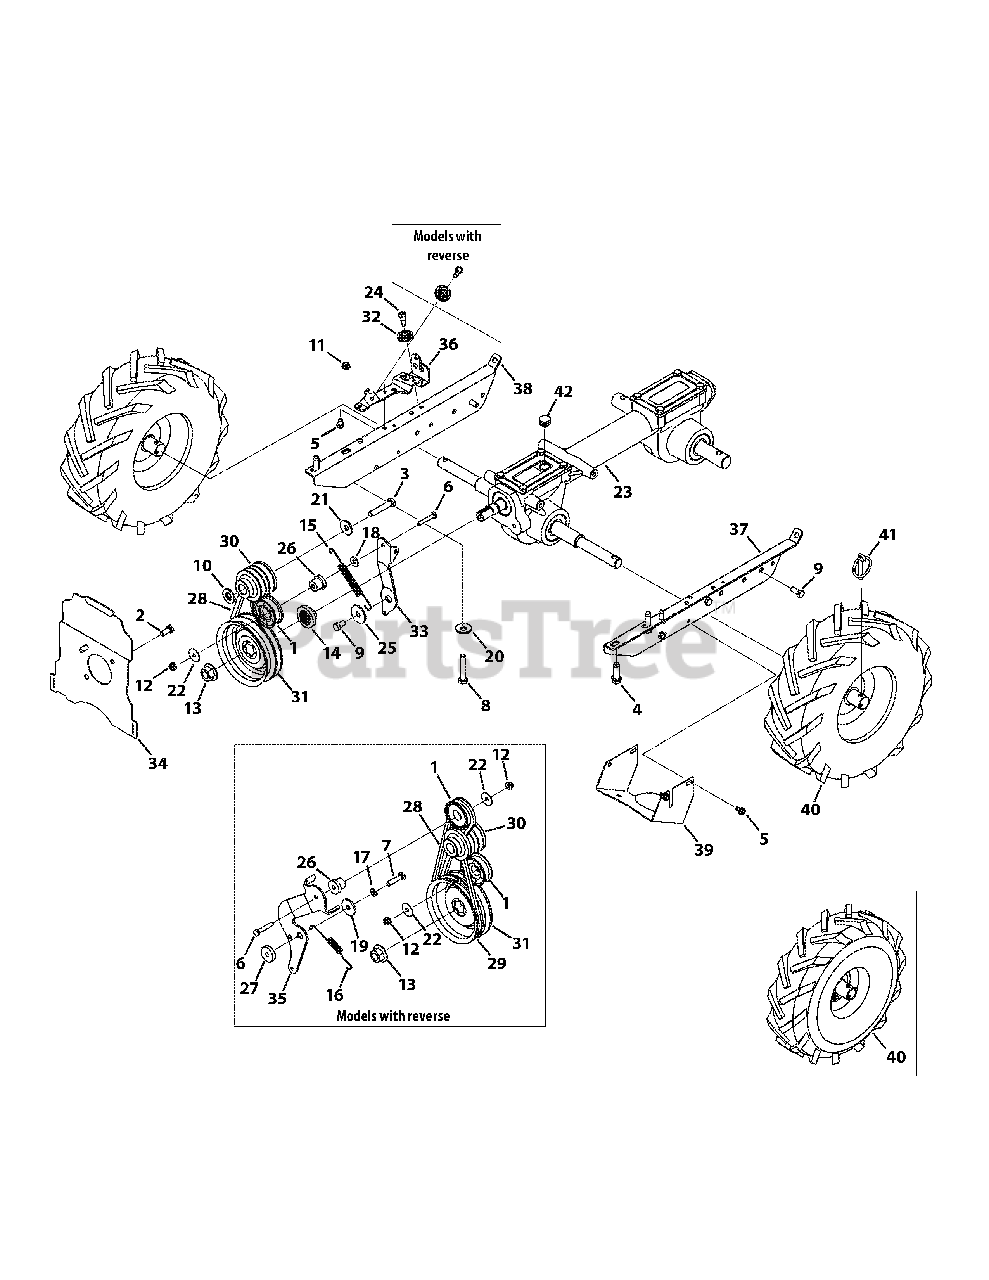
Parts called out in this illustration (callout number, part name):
1	Idler Pulley Assembly, 1.917 OD
2	Hex Head Screw, 5/16-24 x .625
3	Hex Head Screw, 3/8-24 x 2.25, B&S
3	Hex Head Screw, 3/8-24 x 2.00, Honda
4	Screw, 3/8-16 x 1.250
5	Screw, 1/4-20 x 0.500
6	Hex Head Screw, 1/4-20 x 1.50
7	Hex Head Screw, 5/16-24 x 1.25
8	Hex Head Screw, 5/16-18 x 1.50
9	Hex Head Screw, 5/16-18 x .75, Patch
10	Washer, Flat, .760 x 1.50 x .120
11	Flangelock Nut, 5/16-18
12	Flangelock Nut, 1/4-20
13	Flange Nut, 9/16-18
14	Pulley Hub, 5/8 SPLINE
15	Extension Spring, .480 OD x 5.00 LG
16	Extension Spring, LT5 PTO
17	Washer, Lock, 5/16
18	Washer, Flat, .28 x .74 x .063
19	Washer, Flat, .330 x 1.25 x .120
20	Washer, Belleville, .396 x 1.140 x .095
21	Washer, Bell, .396 x 1.140 x .095
22	Washer, Flat, .265 x 1.0 x .030
23	Transmission Assembly
23	Service Transmission Kit
24	Screw, Shoulder, 1/4-28 x .342 x .335
25	Forward Idler Pivot Spacer
26	Spacer, Shoulder, .260 x .785 x .538
27	Reverse Idler Pivot Spacer
28	V Belt, 4L x 25.375 LG
29	V Belt, 3L x 29.125 LG
30	Engine Pulley, 3L & 4L & Honda
31	Transmission Pulley
32	Cable Roller
33	Forward Idler Bracket
34	Cover Mounting Plate
35	Reverse Idler Bracket
36	Pulley Mounting Bracket
37	LH Mount Frame
38	RH Mount Frame
39	Pulley Shield
40	Wheel, 13 x 5 x 6
40	Wheel Assembly, 11 x 4-4
41	Klik Pin, .25 DIA x 1.56
